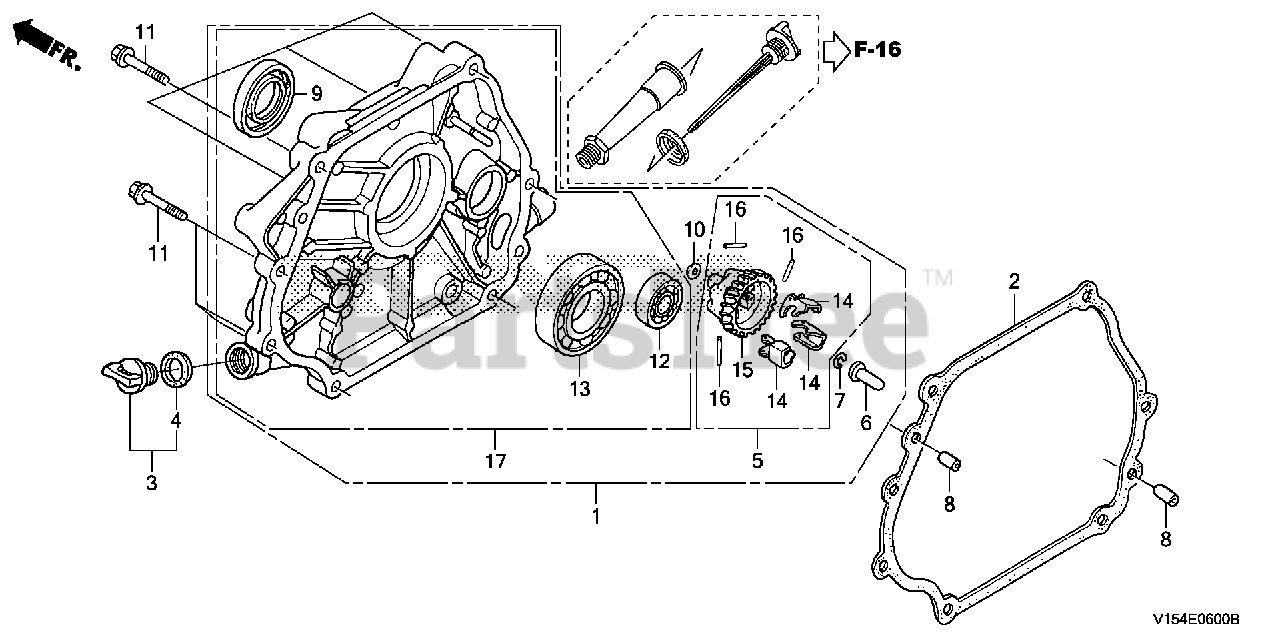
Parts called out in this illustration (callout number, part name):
3	CAP ASSY., OIL FILLER
4	GASKET, OIL FILLER CAP
8	PIN, DOWEL (8X12)
9	OIL SEAL (35X52X8) (NOK)
11	BOLT, FLANGE (8X40) Use up to Engine SN 1003236.
12	BEARING, RADIAL BALL (6202)
13	BEARING, RADIAL BALL (6207)
17	COVER ASSY., CRANKCASE
